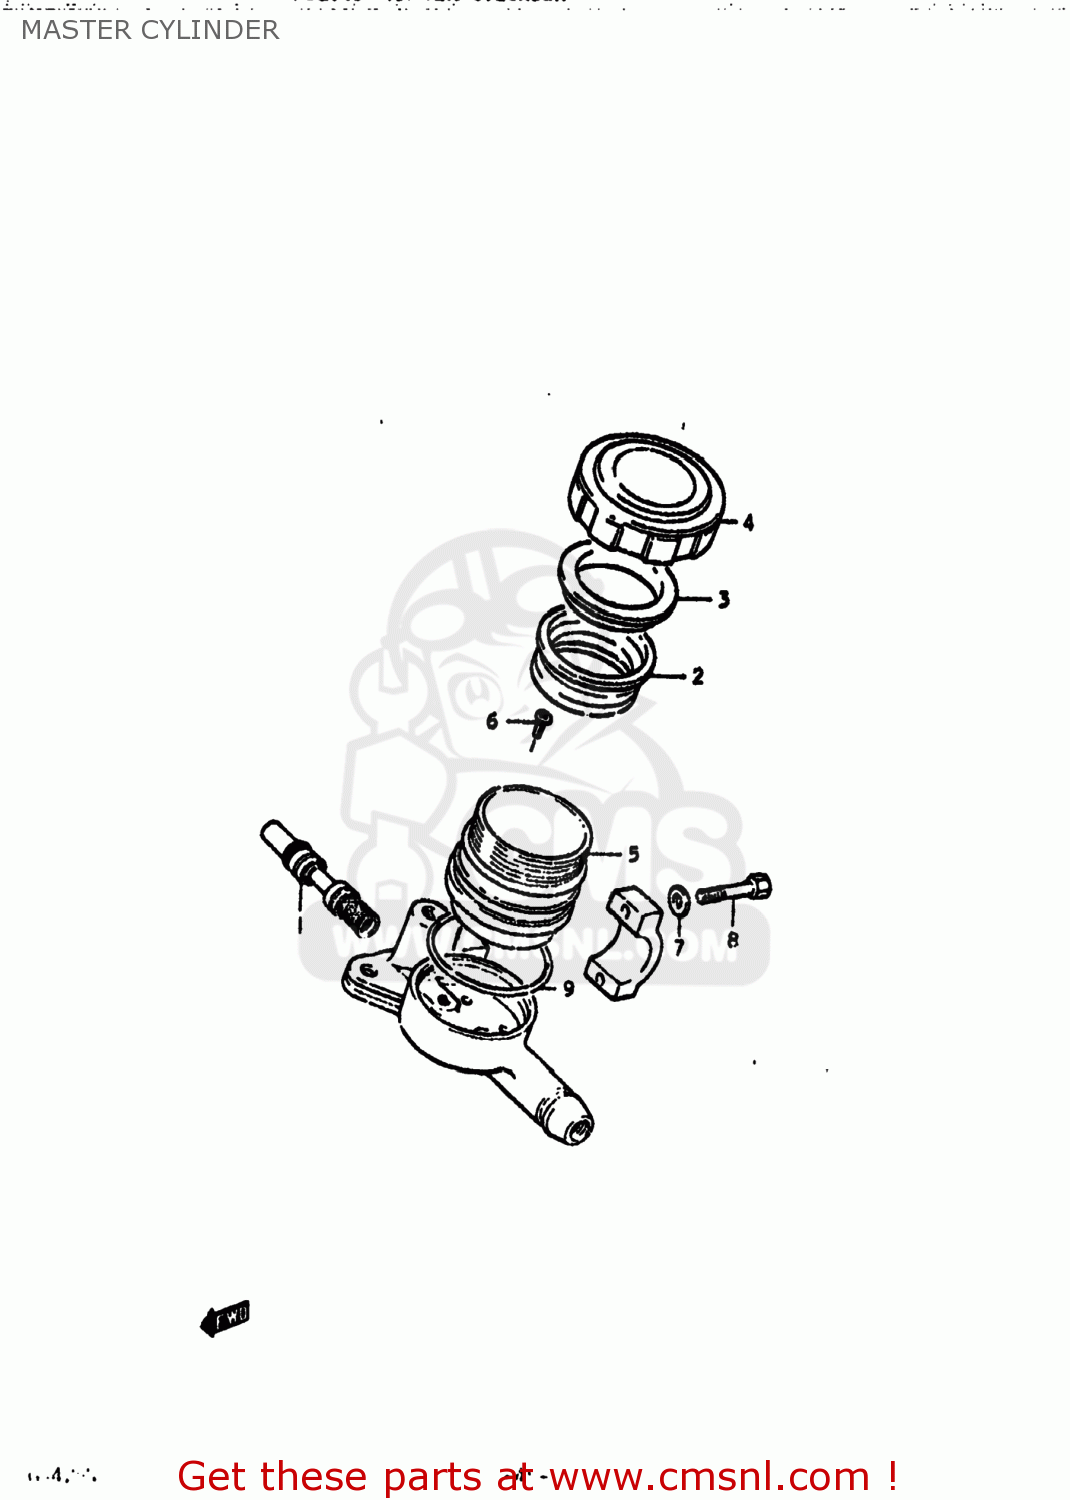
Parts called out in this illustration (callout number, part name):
1	CYLINDER ASSEMBLY,FRONT MASTER
2	DIAPHRAGM,MASTER CYLINDER
3	PLATE,DIAPHRAGM
4	CAP
5	RESERVOIR
6	SCREW,MASTER CYLINDER
7	WASHER
8	BOLT
9	O RING
